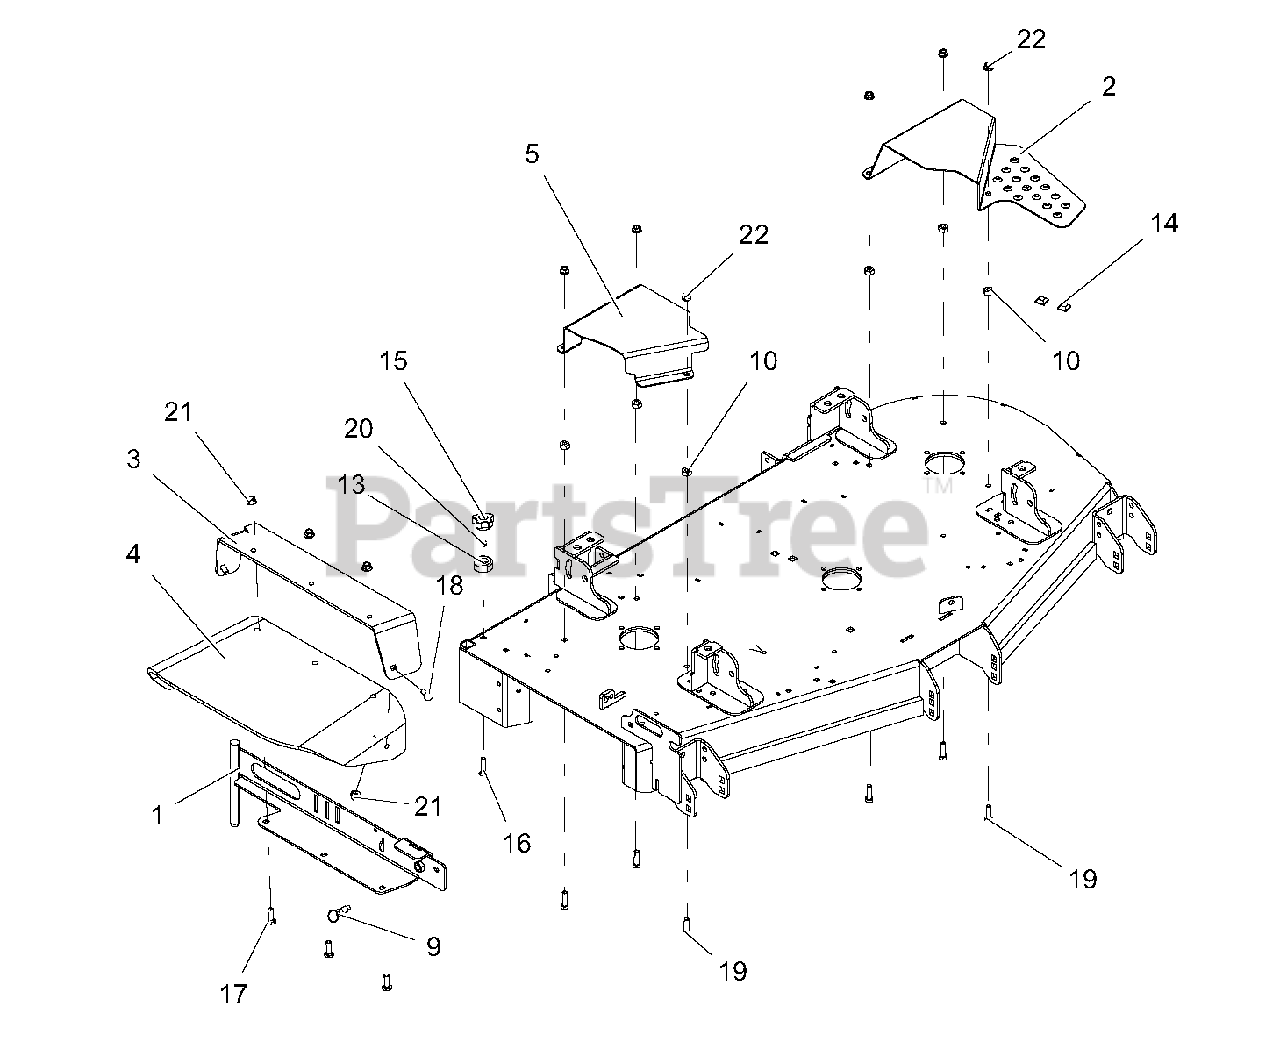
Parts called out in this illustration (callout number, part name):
1	WLDMT, 52"-60" DISCH CHUTE MTG-RED
2	GUARD, 52" LH DECK BELT
3	SUPPORT, CHUTE MOUNTING BRACKET-RED
4	CHUTE, RUBBER DISCHARGE
5	GUARD, 48"-52" RH DECK BELT-RED
9	PULL PIN,.50-13THDX.310 PLNGR
10	NUT-HEAVY HEX .38-16 YWZC
13	BUMPER, RECESSED 1.50 X .63 W/.31 HOLE
15	KNOB, CLAMPING
16	BLT-RDHDSQNK .31-18X1.50 G5 YWZC
17	BLT-RDHDSQNK .38-16X1.25 G5 YWZC
18	BLT-RDHDSQNK .38-16X1.00 G5 YWZC
19	BLT-HEX .38-16X1.25 GR5 YWZC
20	NUT-LK-CTR .31-18 YWZC
21	NUT-LK-NYL-FLG .38-16 YWZC
22	@NUT-SPNLK-FLG .375-16 YWZC
